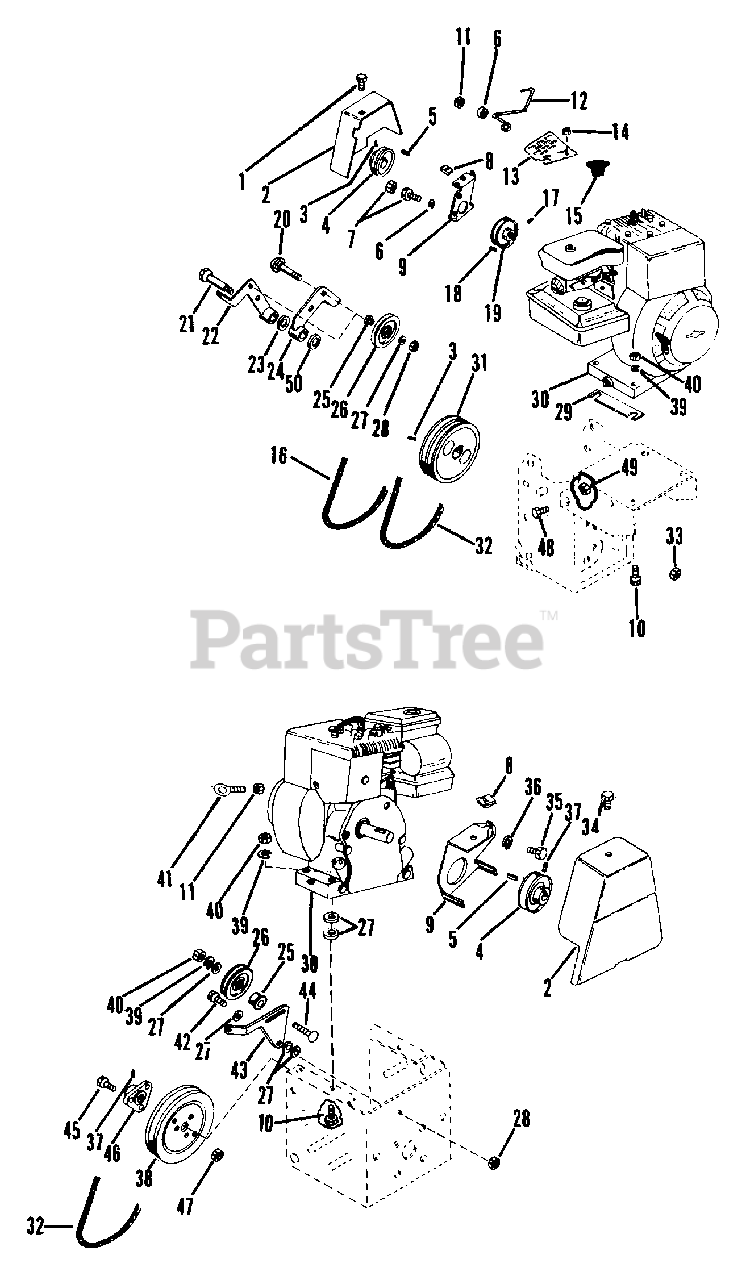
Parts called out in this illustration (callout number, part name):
1	BLT-HEX .25-20X.50 PL GR2
2	BELT COVER
3	SCR-SET .25-20X.38 SKHCUP OH
4	ENGINE SHEAVE
5	KEY-SQ .188X1.0X.188 SAE 8630
6	WSHR-FL-STL.281X.62X.065 PL
7	NUT-LK-FLG .250-20 PL
8	NUT-SPEED U-TYPE .312-18
8	NUT-SPEED U-TYPE .250-20
9	BELT GUARD BRACKET
9	BELT FINGER & COVER BRACKET
10	BLT-HEX .31-18X1.75 PL GR2
11	NUT-LK-CTR .250-20 PL
12	BELT FINGER
14	NUT-FLG. .312-18 PL
16	V-BELT, 3L-WRAPPED
17	SCR-SET .25-20X.25 SKHCUPNY OH
18	KEY-WDRF .125X.625X.250 SAE5
19	REVERSE SHEAVE
20	BLT-RDHDSQNK .31-18X1.25 SHTPL
21	WHEEL SHOULDER BOLT
22	IDLER ARM REV.
23	WSHR-FL-STL .520X.827X.062 YZ
24	IDLER ARM FWD
25	SPCR, BRG .315X.50X.688X.281
26	IDLER
26	Idler
27	WSHR-FL-STL .38X.875X.083 PL
28	NUT-LK .312-18 GR A PL
29	SHIM
30	2 HP B&S ENGINE
30	4 HP BRIGGS ENGINE
31	PLY-DBLV 5.50 X.75 W/KEY SALEM
32	V-BELT, 4L-WRAPPED
32	V-BELT, 4L-RAW EDGE
33	NUT-LK-CTR .375-16 GR A PL
34	BLT-HEX .31-18X.50 PL GR2
35	BLT-HEX .75-16X2.50 PL GR5
36	WSHR-LK .500X.151 HVY PL
37	SCR-SET .32-18X.38 SKHCUPNL OH
38	SHEAVE
39	WSHR-LK .312X.097 PL HVY
40	NUT-HEX .312-18
41	ROD HANGER EYEBOLT
42	BLT-HEX .31-18X1.00 PL GR 2
43	IDLER BRACKET
44	BLT-RDHDSQNK .31-18X1.38SHT PL
45	BLT-SERRDHD SL .31-18X.75 YZ
46	HUB
47	NUT-FLG. .312-18 PL
48	BLT-HEX .38-16X.75 PL GR5
49	NUT-LK TOP .375-16 GR C YWZC
50	WSHR-FL-STL .531X1.062X.095 PL
